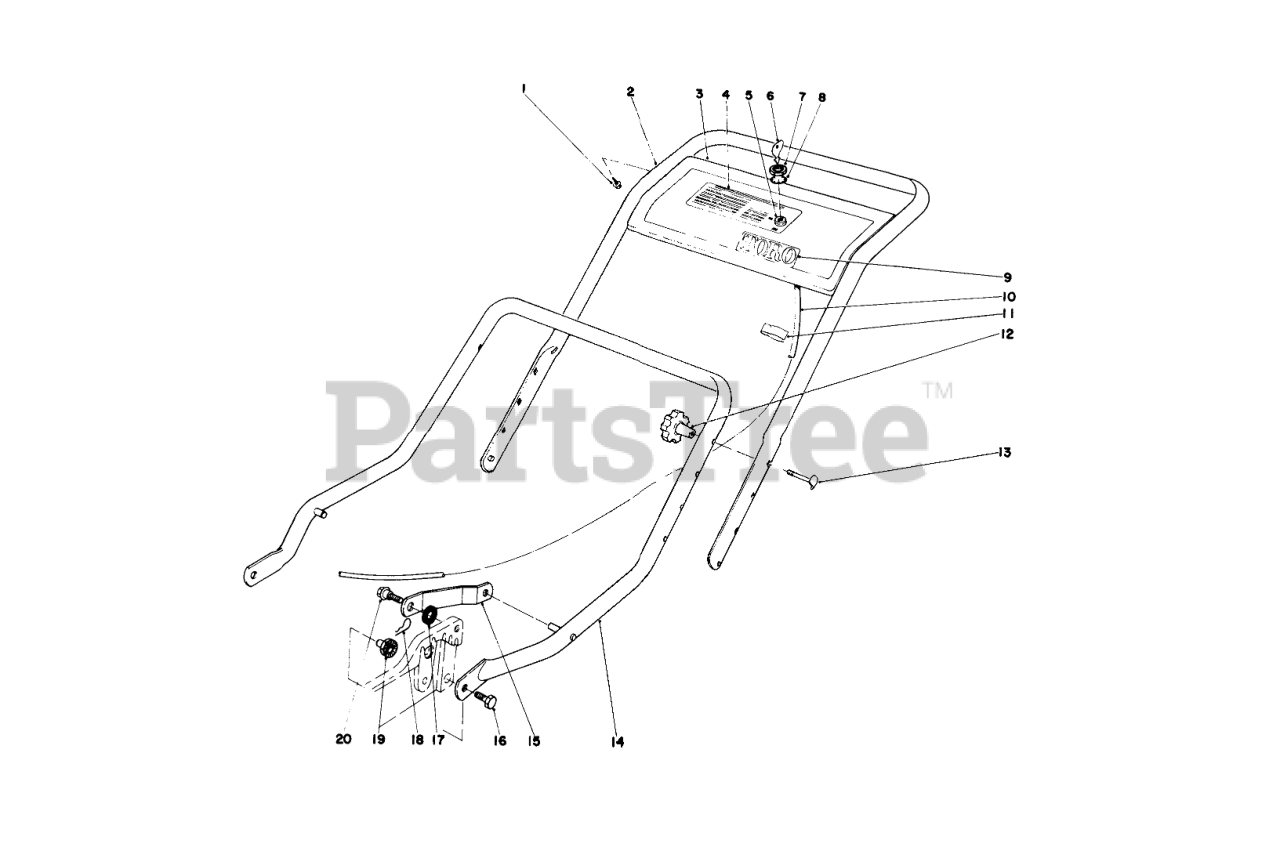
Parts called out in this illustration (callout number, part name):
1	SCREW-HWHTF
2	Upper Handle
3	Control Plate
4	Decal-Control Plate
5	Switch
6	Key
7	NUT-HH
8	WASHER-TOOTH, INTERNAL
9	TORO LOGO DECAL
10	Wire Harness
11	BOWDEN CLIP
13	HANDLE SCREW
14	Lower Handle
15	HANDLE LATCH
16	SCREW-HH
17	SPACER
18	PIN-COTTER, HAIR
19	HANDLE PIVOT NUT
20	SCREW-SHOULDER
